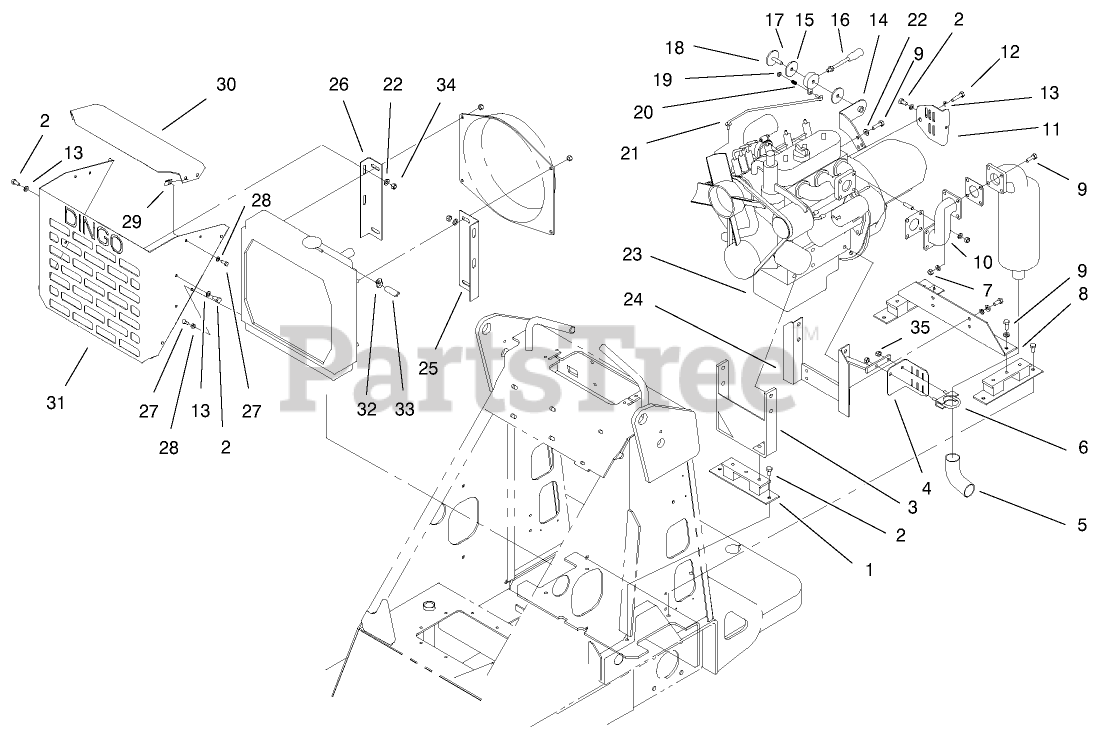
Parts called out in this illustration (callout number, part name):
1	MOUNT-ENGINE, RUBBER
2	SCREW-HH
3	MOUNT-ENGINE, FRONT
4	EXHAUST HEAT SHIELD, LOWER
5	TAILPIPE-MUFFLER
6	U-BOLT
7	Nut
8	SUPPORT-ENGINE
9	Bolt
10	TUBE-MOUNT, MUFFLER
11	EXHAUST-HEAT SHIELD, MUFFLER
12	SCREW
13	WASHER-LOCK
14	BRACKET-THROTTLE
15	CONTROL-THROTTLE
16	LEVER - VALVE
17	SPACER-THROTTLE
18	RETAINER-THROTTLE
19	NUT-LOCK
20	SPRING-THROTTLE
21	LINKAGE-THROTTLE
22	WASHER-PLAIN
23	ENGINE ASM-KUBOTA
24	MOUNT-ENGINE, REAR
25	RADIATOR MOUNT, BRKT-LH
26	RADIATOR MOUNT, BRKT-RH
27	SCREW-HH
28	WASHER-LOCK
29	CLIP-M6-1.0
30	GUARD-FAN
31	SHROUD-RADIATOR
32	CLAMP-WORM
33	HOSE-FUEL
34	NUT-LOCK, NI
35	NUT-LOCK, NI
